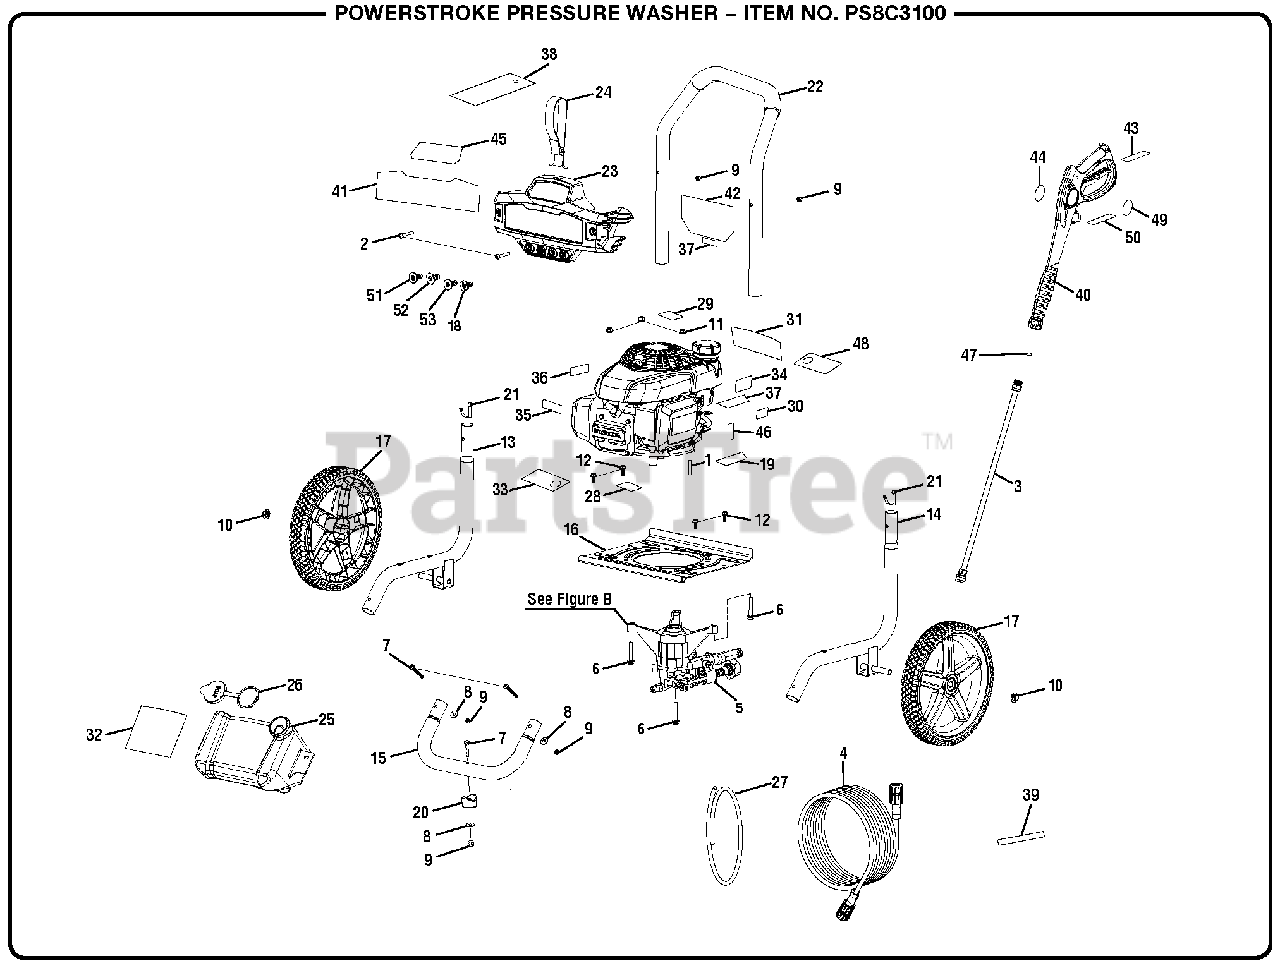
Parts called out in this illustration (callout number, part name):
1	Output Shaft Key
2	Bolt (M6 x 42 mm, T30 Torx Pan Hd.)
3	Spray Wand
6	Bolt (M8 x 60 mm, Hex Hd.)
7	Screw (M6 x 48 mm, T-30 Torx Hd.)
8	Washer (1/4 in.)
9	Lock Nut (M6)
11	Lock Nut (M8)
12	Bolt (M6 x 16 mm, Hex. Flange Hd.)
13	Left Frame Assembly
14	Right Frame Assembly
15	Front Frame Assembly
16	Engine Plate
18	Soap Nozzle
19	EMC ICES-2/NMB-2 Label (Canada)
21	Handle Spring Clip
22	Handle Assembly
23	Hose and Nozzle Holder Assembly
24	Hose Holder Strap
25	Soap Tank
26	Soap Tank Cap
27	Chemical Siphon Tube
28	Add Oil Label
29	Combustion Warning Label (English/French)
30	Choke Label
31	Danger Label (English/French)
32	Soap Tank Label
33	Oil Dipstick Hangtag
34	E85 Label
35	Logo Label (Honda)
36	Hot Surface and Exhaust Label
37	Inquiries Label
38	Nozzle Hangtag
39	Hose Label
40	Trigger Handle Assembly
41	Performance Label
42	Quick Start Label
43	Trigger Handle Warning Label (French)
44	Powerstroke Spray Wand Logo Label
45	Logo Label
46	Engine Label (On-Off)
47	O-Ring (9.5 x 2.65, NBR Shore A 90)
48	Danger Hangtag
49	Trigger Handle Warning Label (English)
50	Trigger Handle Specifications Label
51	0deg Nozzle
52	25deg Nozzle
53	40deg Nozzle
